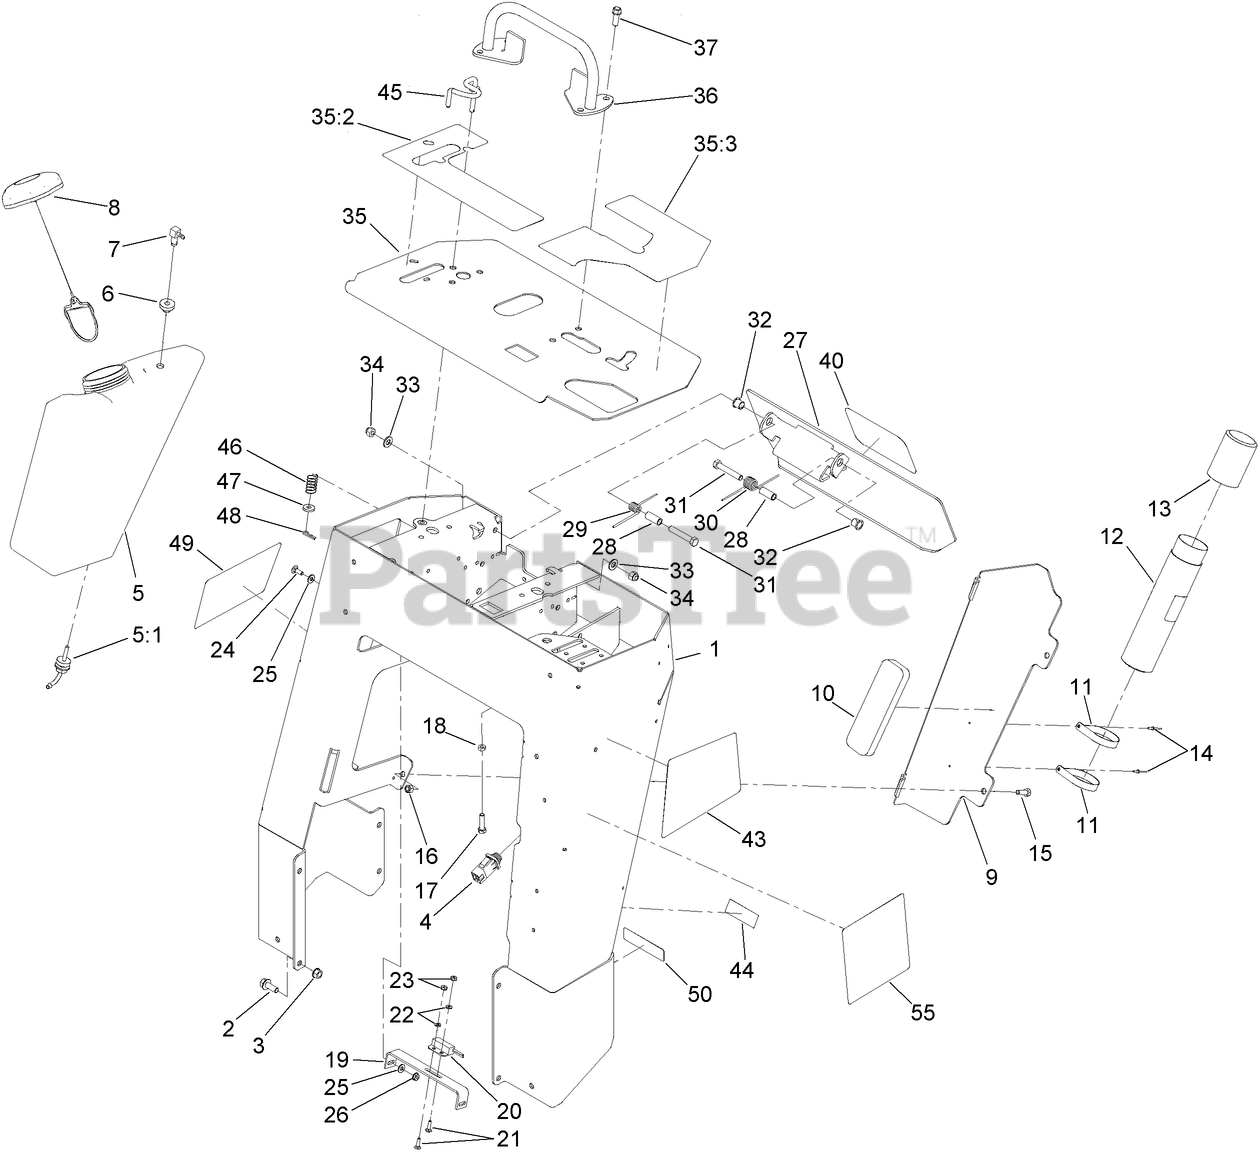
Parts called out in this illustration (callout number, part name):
2	SCREW-HHF
3	NUT-FLANGE
4	SWITCH-PLUNGER
5	TANK-FUEL
5:1	FITTING-FUEL, BULKHEAD
6	BUSHING
7	FITTING-ELBOW, 90 DEG
8	CAP-FUEL, RATCHETING
9	BRACKET-COVER, TANK
10	PAD-FOAM
11	CLAMP-R
12	TUBE-MANUAL
13	CAP-HOUSING
14	RIVET-POP
15	SCREW-HH
16	NUT-LOCK, NI
17	SCREW-HH
18	NUT-JAM
19	PLATE-SWITCH
20	SWITCH-PROXIMITY
21	SCREW-CARR
22	WASHER-FLAT
23	NUT-KEPS
24	BOLT-CARR
25	WASHER-FLAT
26	NUT-KEPS
27	PLATE-REVERSE
28	SPACER-SPRING
29	SPRING-TORSION, LH
30	SPRING-TORSION, RH
31	SCREW-HH
32	BUSHING-NYLINER
33	WASHER-FLAT
34	NUT-LOCK, NI
35	PANEL-CONTROL
35:2	DECAL-CONSOLE, RH
35:3	DECAL-CONSOLE, LH
36	BAR-REFERENCE
37	SCREW-TAPTITE
43	DECAL-SIDE, LH
44	DECAL-INFO
45	ROD-INTERLOCK
46	SPRING-CONTROL
47	WASHER-FLAT
49	DECAL-SIDE, RH
50	DECAL-ARRESTOR, SPARK
55	DECAL-SERVICE
